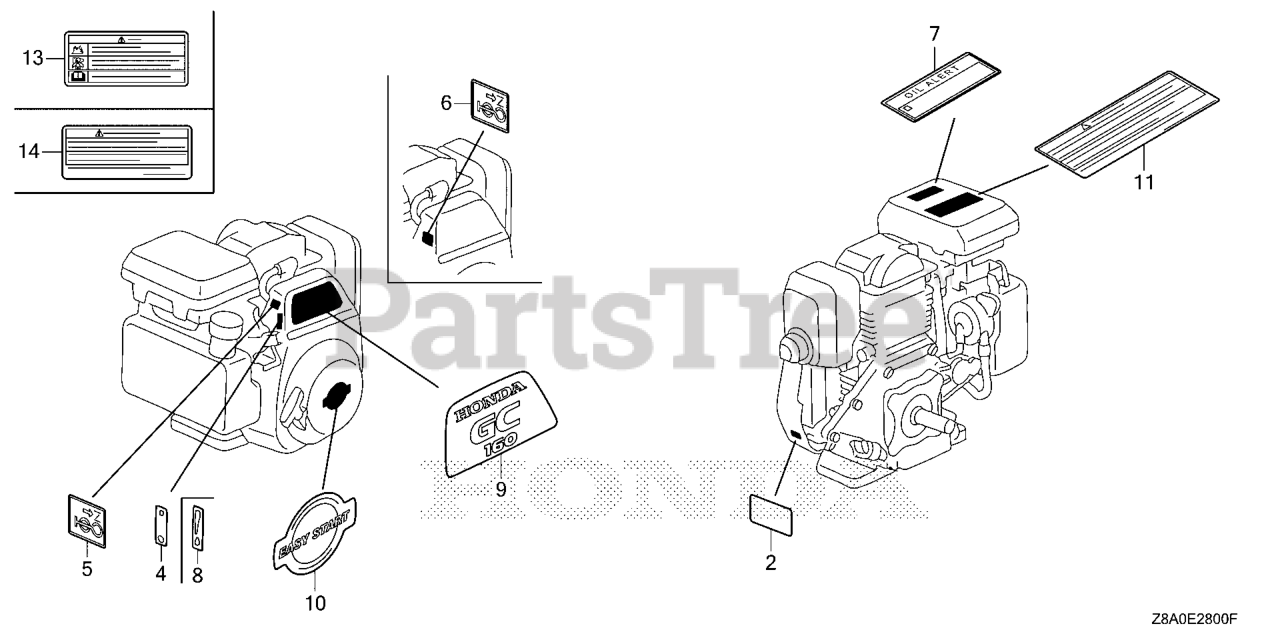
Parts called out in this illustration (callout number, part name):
2	LABEL, WARNING (NOT CERTIFIED FOR SALE)
4	MARK, ENGINE SWITCH INDICATION
5	MARK, CHOKE
7	MARK, OIL ALERT (ENGLISH)
9	EMBLEM (GC160)
10	MARK, RECOIL COVER
11	MARK, OPERATOR CAUTION (ENGLISH)
